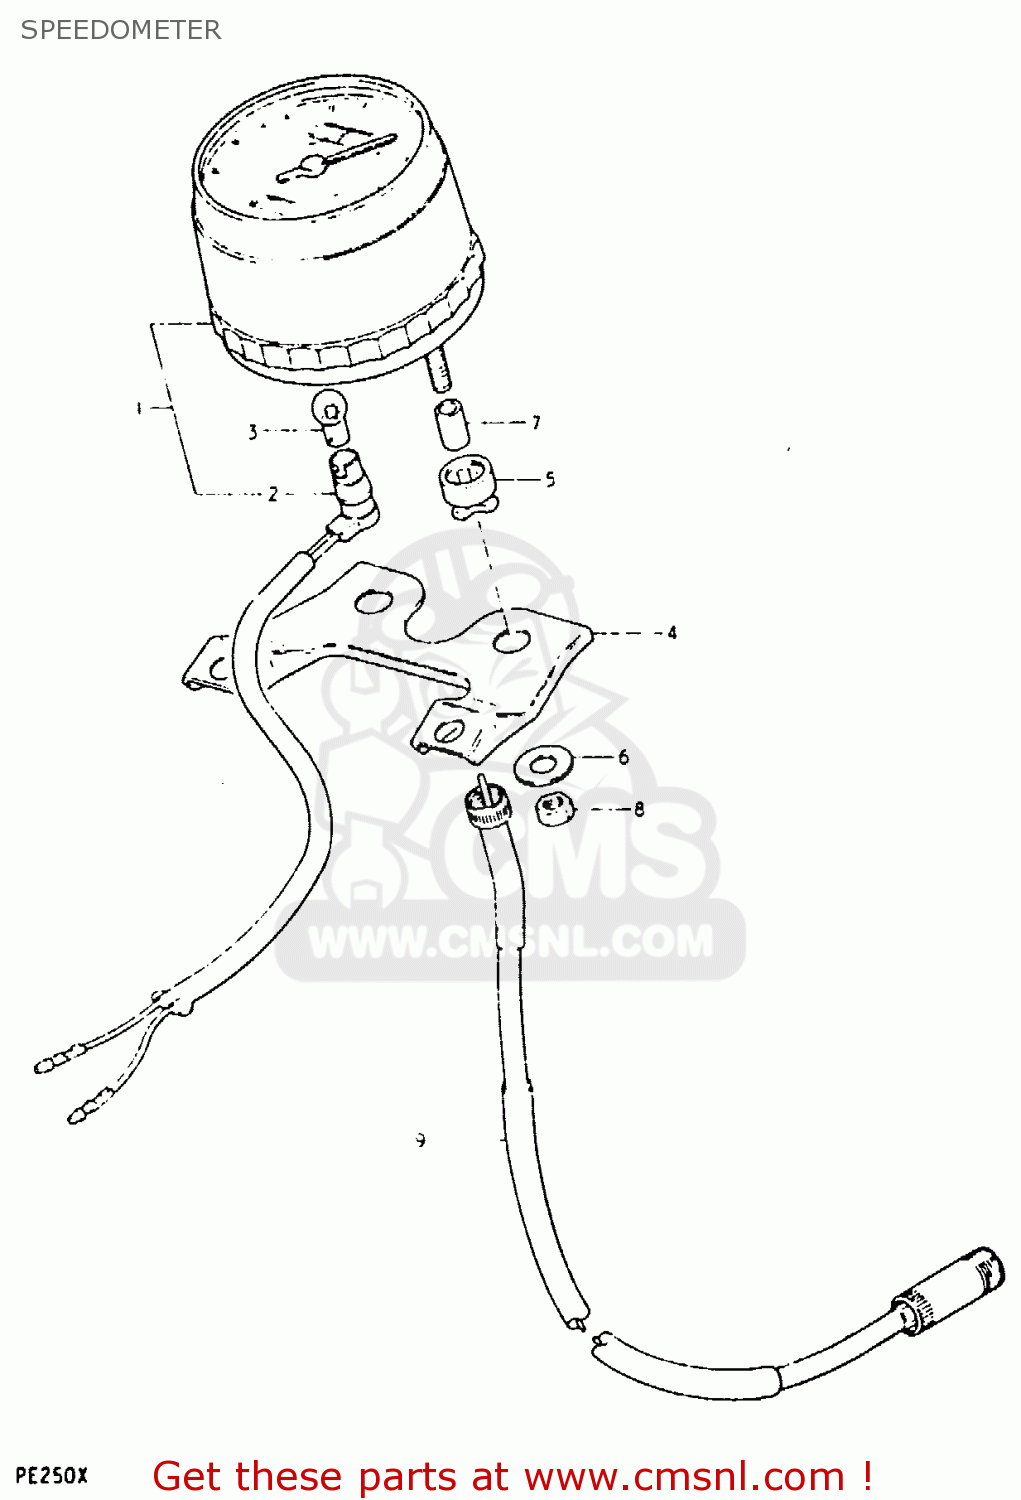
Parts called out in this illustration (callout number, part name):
1	SPEEDOMETER ASSEMBLY
2	SOCKET,METER
3	BULB(6V1.7W,STANLEY,A61A)
4	BRACKET,SPEEDOMETER
5	CUSHION,SPEEDOMETER
6	WASHER
7	SPACER,METER
8	NUT
9	CABLE ASSEMBLY,SPEEDOMETER
